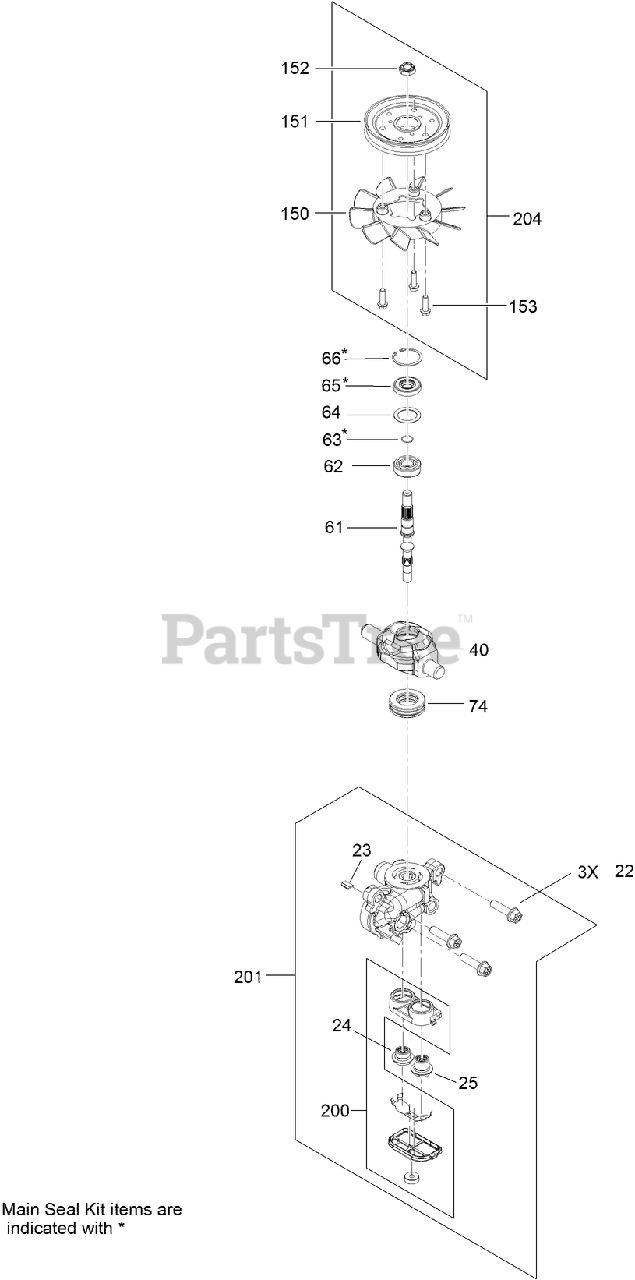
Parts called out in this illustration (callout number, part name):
22	SCREW-HFHC
23	PLATE-BYPASS
24	CHECK PLUG ASM
25	CHECK PLUG ASM
40	TRUNNION-PLATE, SWASH
61	SHAFT-INPUT
62	BEARING-BALL
63	RING-RETAINING, WIRE
64	SPACER
65	SEAL-LIP
66	RING-RETAINING
74	BEARING-THRUST, BALL
150	FAN
151	PULLEY ASM
152	NUT-HEX JAM
200	FILTER KIT
201	CENTER SECTION KIT
204	FAN PULLEY KIT
